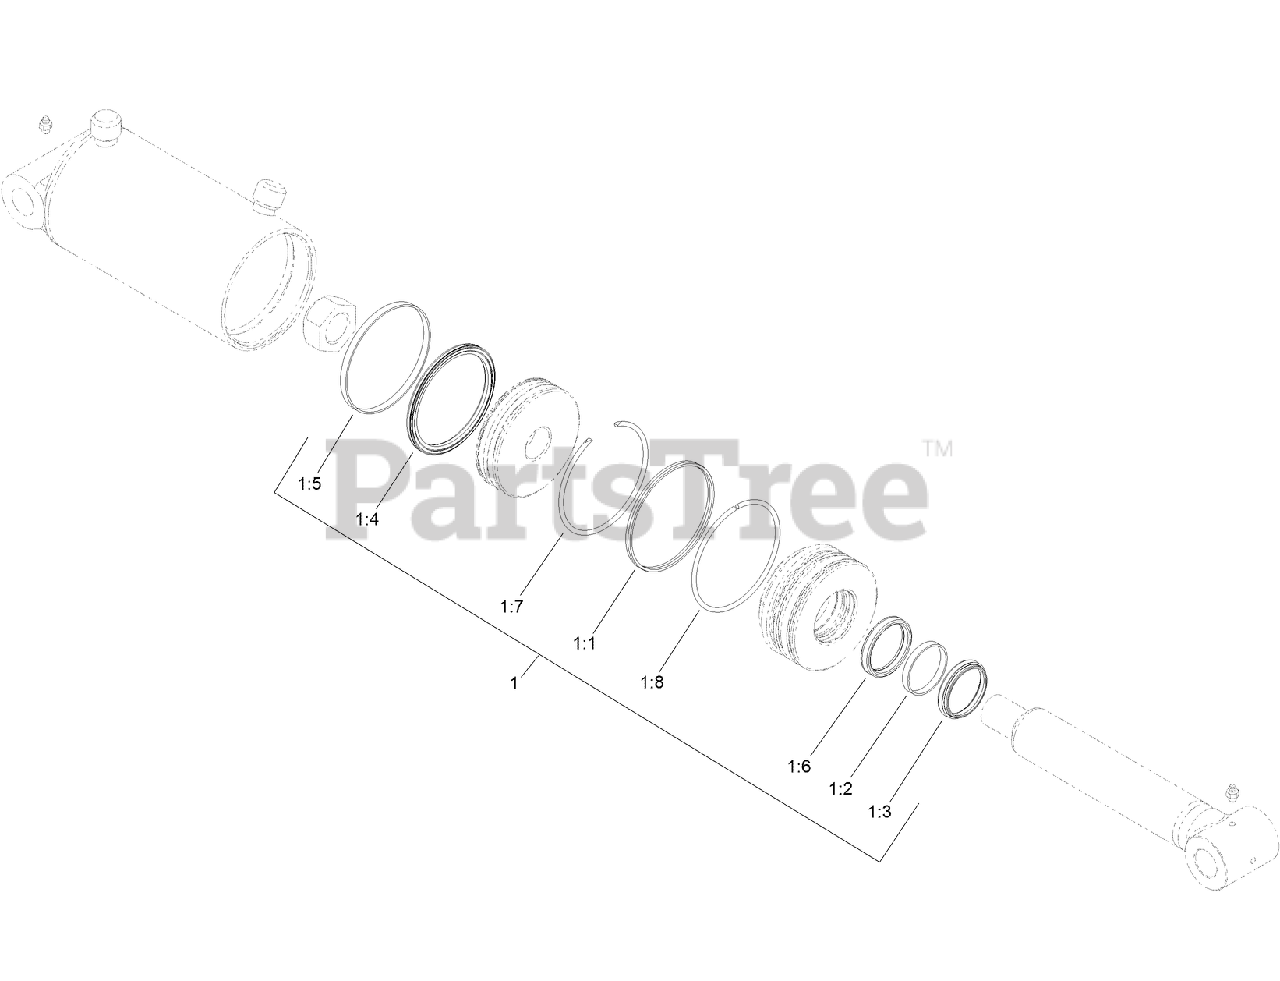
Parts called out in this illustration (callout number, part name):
1	SEAL REPAIR KIT
1:1	SEAL-DUAL
1:2	Deck ASM
1:3	Deck ASM
1:4	Deck ASM
1:5	RING-wear, piston
1:6	RING-WEAR, ROD
1:7	RING-RETAINING, INTERNAL
1:8	RING-RETAINING, EXTERNAL
